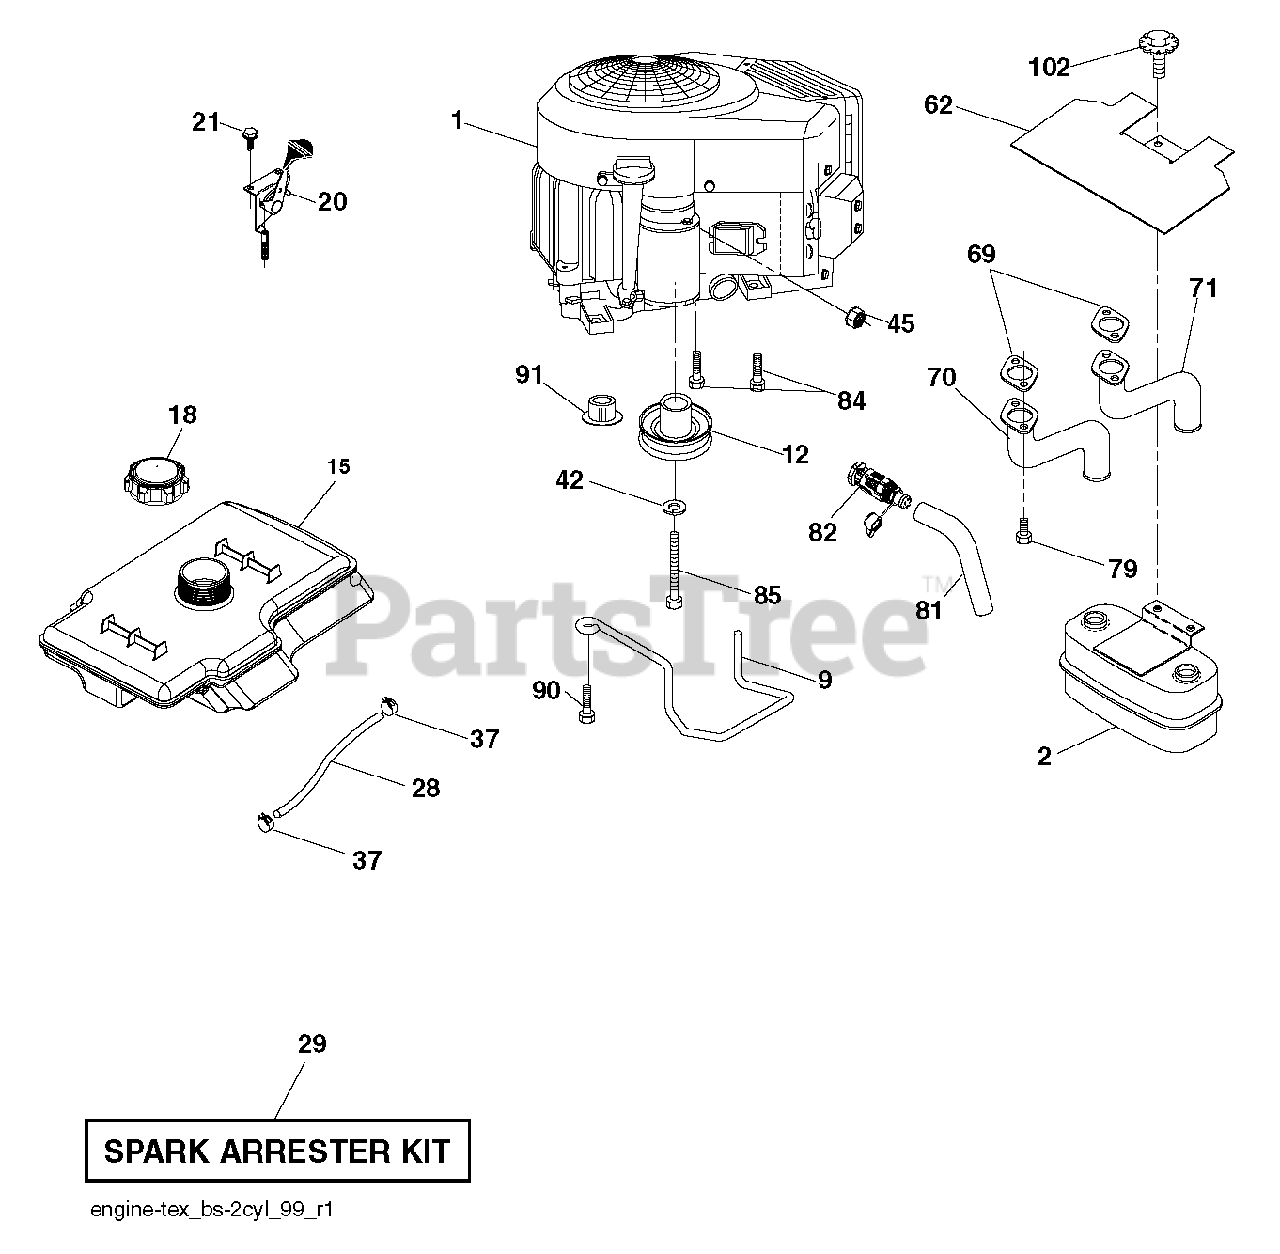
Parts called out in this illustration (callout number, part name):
2	MUFFLER.ASM.TWN.EXTNDED.DFLCTR
9	KEEPER.BELT.ENGINE
12	PULLEY.ENGINE.5.0.PD
18	Fuel Tank Cap Assembly, 3" N-EPA Black
20	CONTROL.TH/CK.COBRA.B&S.TWN.
21	SCREW.#10 X 0.750.BOS (2 2)
28	HOSE.1/4".FUEL.LINE.64".LENGTH
29	KIT.SPARK ARRESTOR(392390 B&S)
37	HOSE CLAMP
42	LOCKWASHER
45	NUT
62	SHIELD.HEAT.MUFFLER
69	GASKET.MUFFLER
70	EXHAUST.TUBE.LH.BS/TWIN
71	EXHAUST.TUBE.RH.B&S.TWIN.INTEK
79	SCREW.SOCKET.HEAD.5/16-18
81	TUBE, DRAIN OIL ASM.
82	VALUE.OIL.DRAIN
84	SCREW.3/8-16
85	BOLT HEX 7/16-20X4-1/4"
90	SCREW 3/8-16X1
91	BUSHING.1.375OD
102	SCREW
